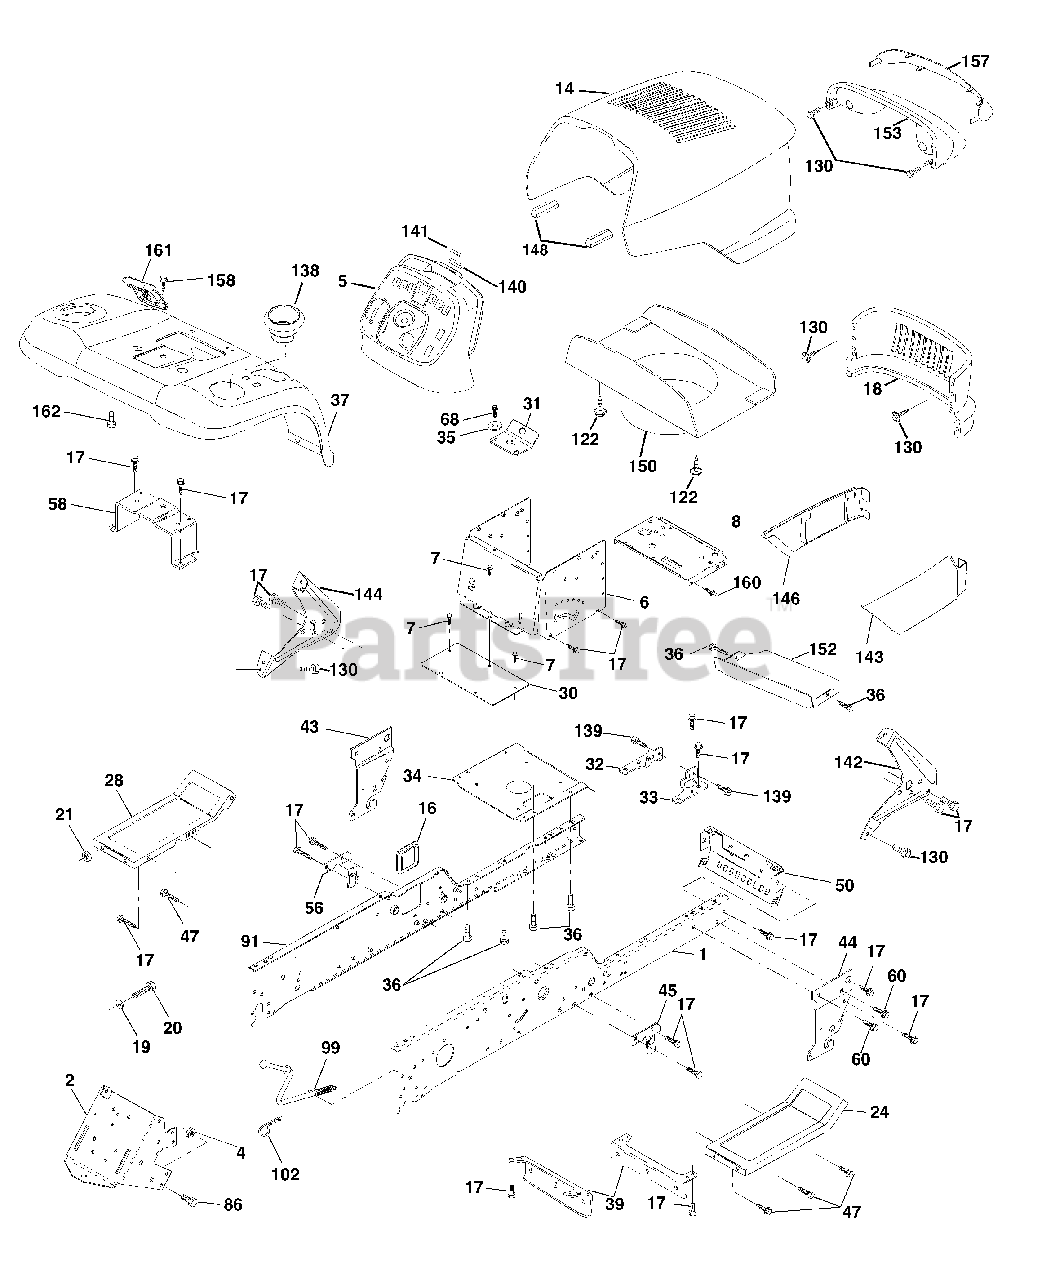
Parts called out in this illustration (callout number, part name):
1	Rail, Frame RH
2	Drawbar, Gt
4	Nut, Crownlock 7/16-14Unc
5	Dash
6	Dash Asm., Lower
7	Screw, Thd Cut 1/4-20 x 1/2
8	Support, Battery
14	Hood Asm., Pnt
16	Cover, Access
17	Screw, 3/8-16 x 3/4
18	Grille
19	Washer 13/32 x 13/16 x 12 Ga.
20	Bolt, Fin Hex 3/8-16 x 1
21	Nut, Crownlock 3/8-16 Unc
24	Footrest, RH
28	Footrest, LH
30	Saddle, Hydro 1995
31	Bracket, Supt 1-pc VGT Steering
32	Bracket, Pivot Chassis LH
33	Bracket, Pivot Chassis RH
34	Plate Asm. Engine Chassis
35	Washer 11/32 x 11/16 x 16 Ga.
36	Screw 5/16-18 x 3/4
37	Fender, Pnt.
39	Bracket, Axle Front
43	Bracket, Spnsn Front Lh
44	Bracket, Spnsn Front Rh
45	Bracket Asm., Susp Chassis Rh
47	Screw Thdrol 3/8-16 x 1/2 TYT
50	Bracket, Chassis Front
56	Bracket Asm., Susp Chassis Lh
58	Bracket Asm., Fender
60	Screw 3/8-16 x 1-1/4
68	Screw, Thd 5/16-18 x 1/2
86	Bolt, Fin Hex 7/16-14 Unc x 1
91	Rail, Frame Lh
99	Rod By Pass
102	Retainer, Spring
122	Screw Hex Wshd 8-18 x 7/8
130	Screw HWHD Hi-Lo #13-16 x 3/4
138	Cupholder YTGT
139	Bolt Shoulder 5/16-18 TT
140	Magnet YTGT
141	Stricker Plate YTGT
142	Bracket Dash RH
143	Skirt Grill RH
144	Bracket Dash LH
146	Skirt Grill LH
148	Extrusion Bumper
150	Duct Heat Hood
152	Shield Browning
153	Light Box Asm. w/Lens
157	Lens, Bar
158	Screw Thdrol 3/8-16 x 1/2
160	Screw 5/16-18 x 1/2
161	Console Fuel Window
162	Screw 1/4-1/2
